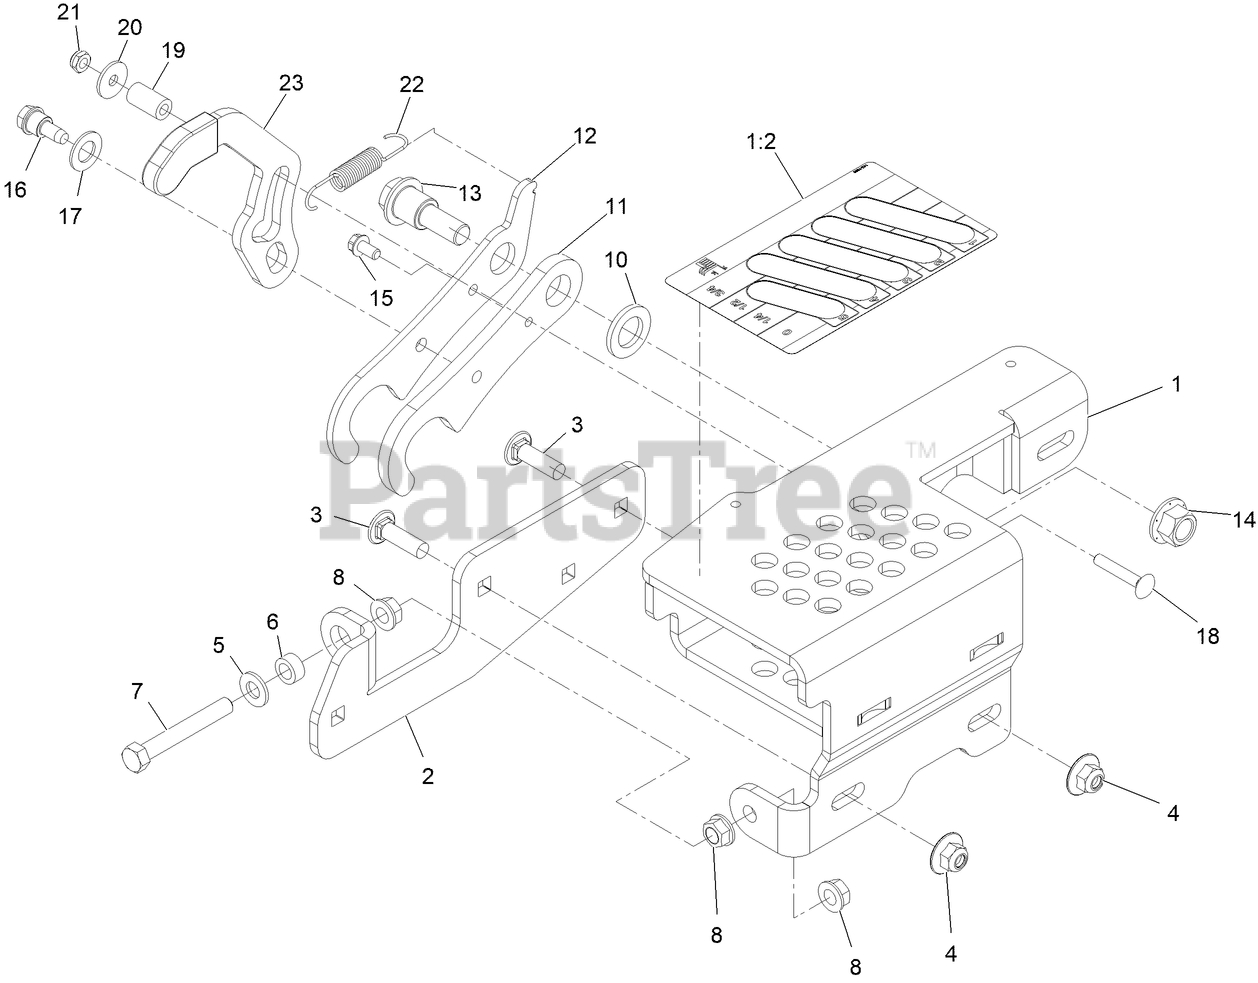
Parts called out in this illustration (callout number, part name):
1	ASM- Box HOC W/Decal
1:2	Decal- Height Of Cut
2	Bracket- Mount HOC
3	Bolt-Carriage 3/8-16 X 1 1/4
4	Nut-Nyloc 3/8-16 Flg
5	WASHER-FLAT
6	Spacer
7	SCREW-TAP
8	NUT-HHF, WHIZ
11	Plate- Pawl
12	Plate- Pawl
13	SCREW-SHOULDER, HHF 1/2-13 X 1.12
14	Nut-Lock 1/2-13
15	SCREW-HWH
16	BOLT-SHOULDER
17	SPACER
18	SCREW-CARR
19	Spacer- 0.50" OD
21	NUT-LOCK, NI
22	Spring- Extension
23	Lever- Transport W/Grip
